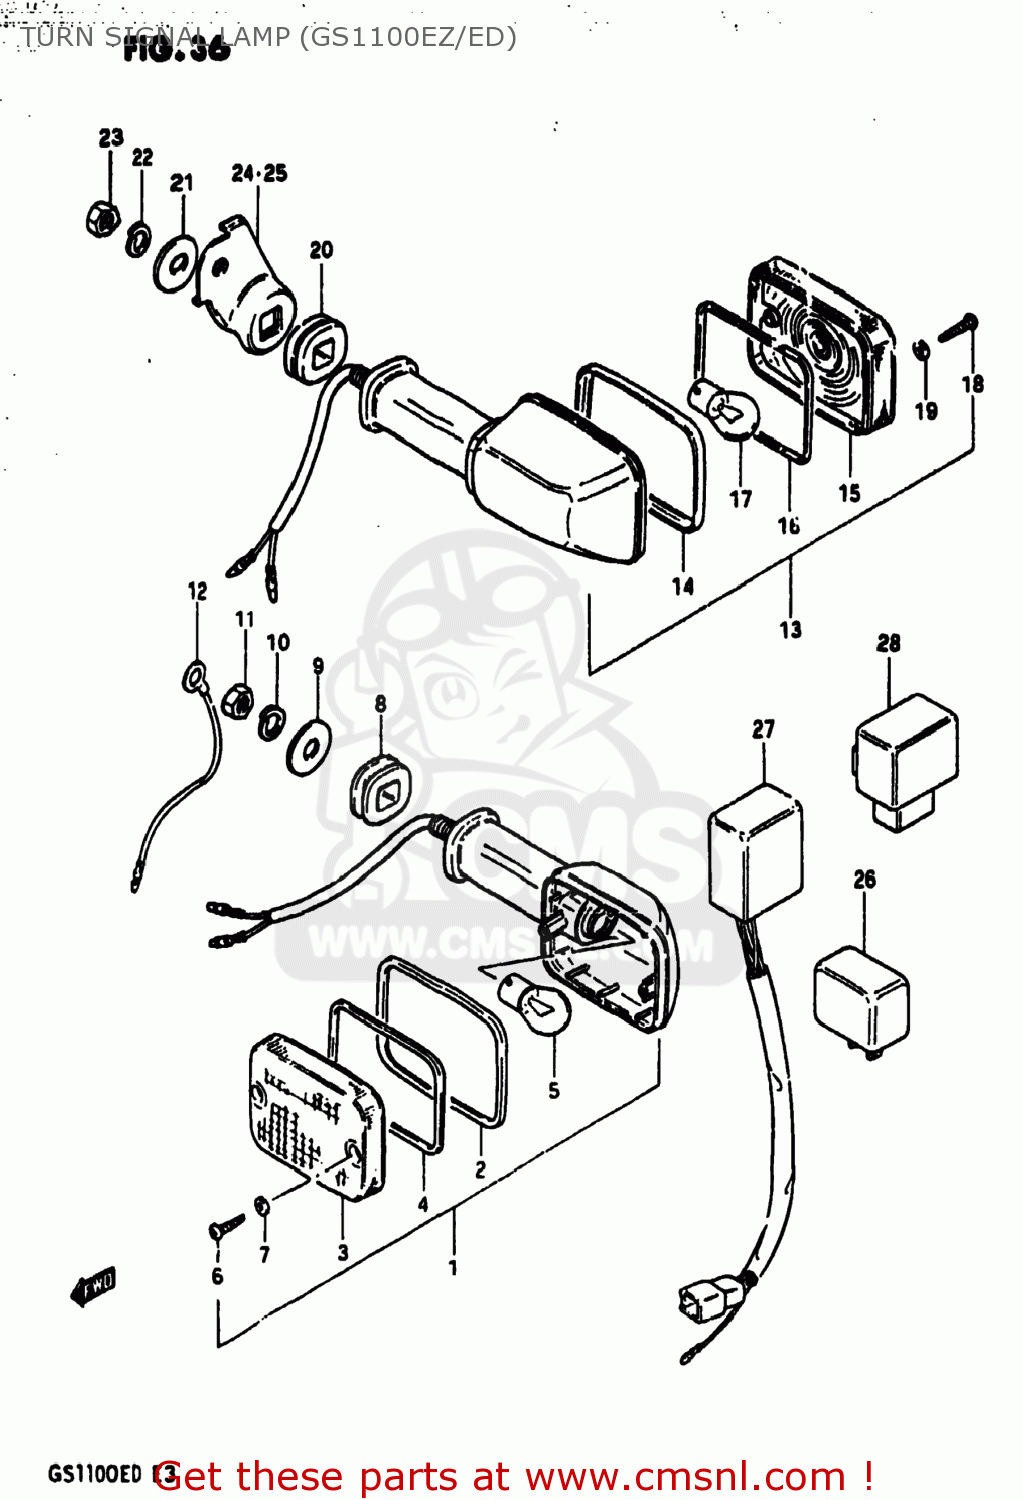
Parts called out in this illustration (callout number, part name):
1	LAMP ASSEMBLY,REAR TURN SIGNAL
2	RIM
3	LENS
4	GASKET (NAS)
5	BULB(12V23W)
6	SCREW
7	GASKET (NAS)
8	CUSHION
9	WASHER (10.5X30X2.3)
10	LOCK WASHER
11	NUT
12	WIRE
13	LAMP ASSEMBLY,FRONT TURN SIGNAL
14	RIM
15	LENS
16	GASKET (NAS)
17	BULB(12V23W,STANLEY,A4577A)
18	SCREW
19	GASKET (NAS)
20	CUSHION
21	WASHER (10.5X30X2.3)
22	LOCK WASHER
23	NUT
24	BRACKET,REAR TURN SIGNAL
25	BRACKET,RR TURNSIGNAL LAMP,L
26	RELAY ASSY,TURNSIGNAL
27	UNIT,TURN SIGNAL CONTROL
28	UNIT,TURN SIGNAL CONTROL
